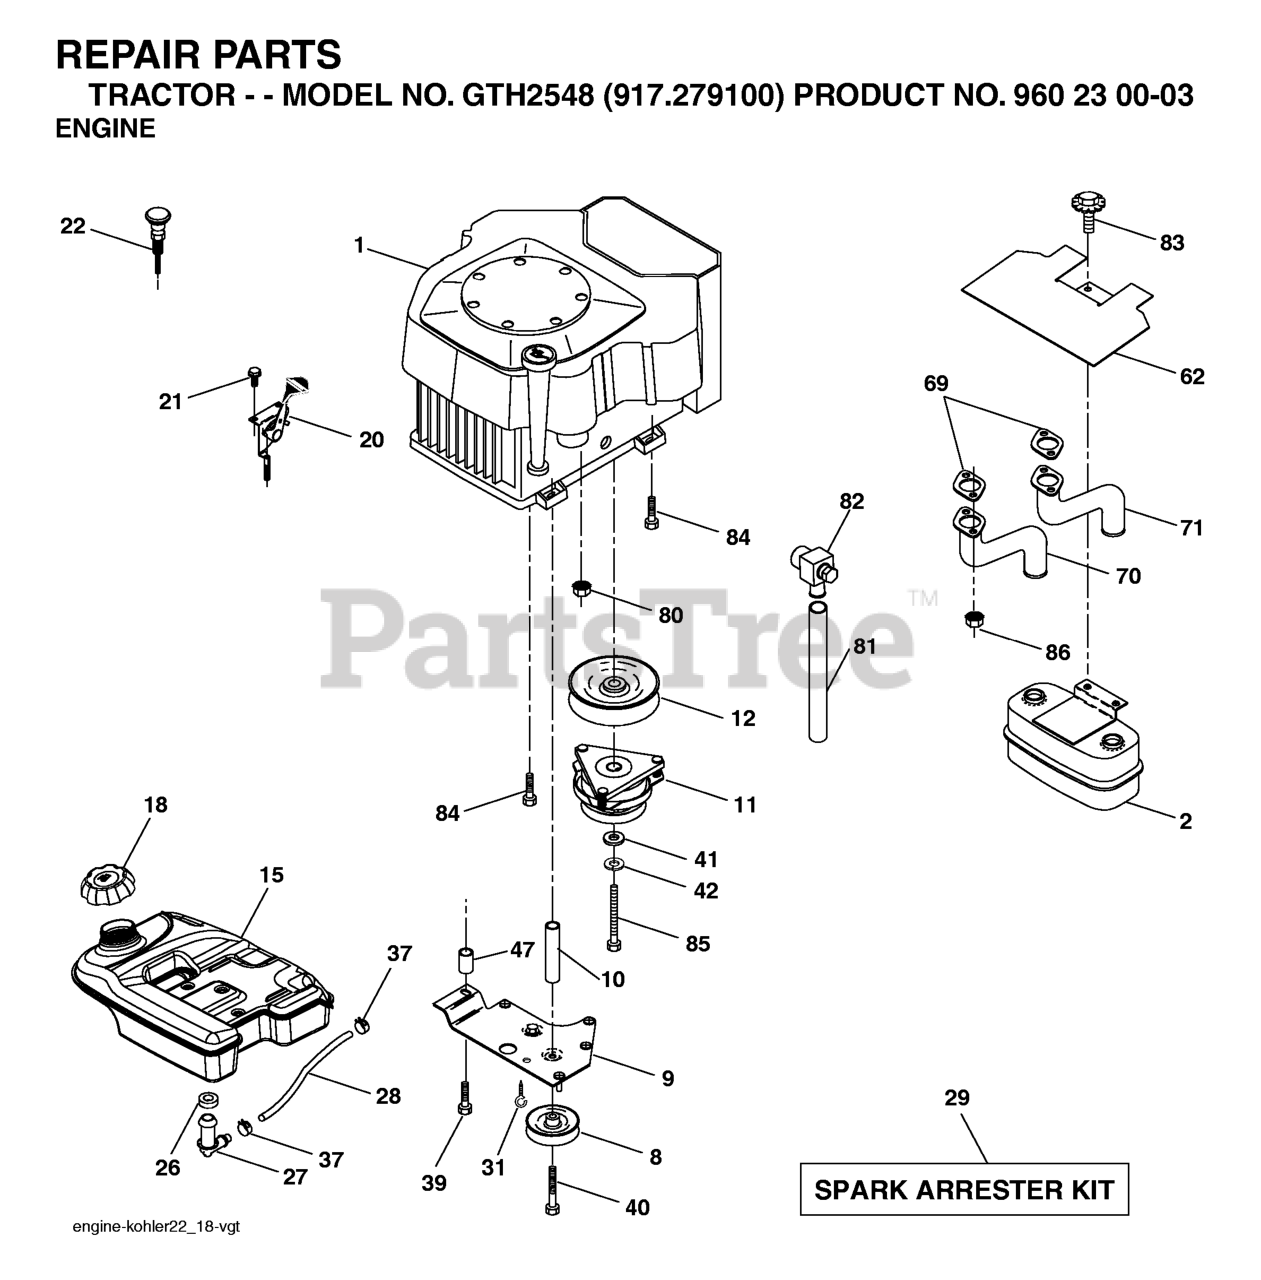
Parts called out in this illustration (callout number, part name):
2	MUFFLER.TWIN.CYL.LOW.TONE
8	RP.IDLER GROOVED
9	KEEPER ASM BELT ENGINE
11	CLUTCH MZ ZTR GT.48/54"1.125"
12	PULLEY ENG VGT ELECT CLUTCH
15	TANK.FUEL.5.0 LEFT.FILL.YTGT
18	TANK CAP
20	THROTTLE CONTROL
21	SCREW
22	CONTROL, CHOKE
26	BUSHING OUTLET T
27	STEM FUEL TANK
28	HOSE
29	KIT.SPARK ARRESTOR 794945 B&S
37	HOSE CLAMP
39	SCREW TT 3/8-16X2-1/4 UNC
40	Screw TT 3/8-16 x 4 unc
42	LOCKWASHER
43	BOLT HEX 7/16-20 X 3.75 GR. 5
62	RP SHIELD HEAT MUFFLER
69	GASKET.EXHAUST.KOHL.CV18-CV26
80	FLANGE NUT
81	TUBE, DRAIN, OIL
83	BOLT.5/16-18UNCX3/4 W/SEMS.BLK
84	SCREW 3/8-16 X 1-1/2
86	NUT.HEX.FLANGE.TOPLOCK
